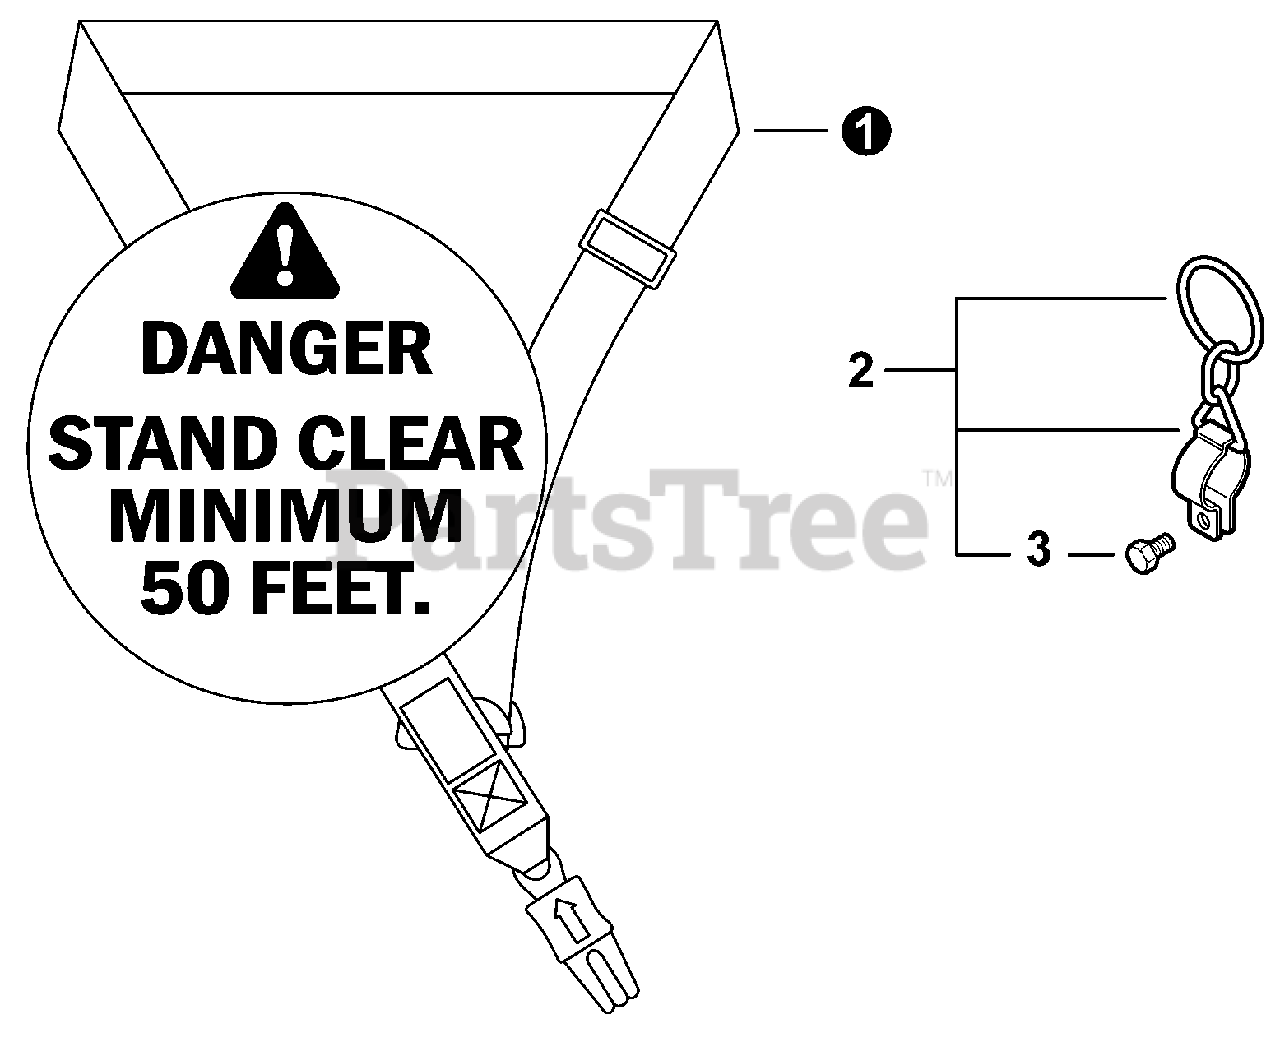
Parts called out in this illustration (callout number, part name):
1	HARNESS, SHOULDER
2	HANGER SET, HARNESS
3	BOLT, TORX 5×12
